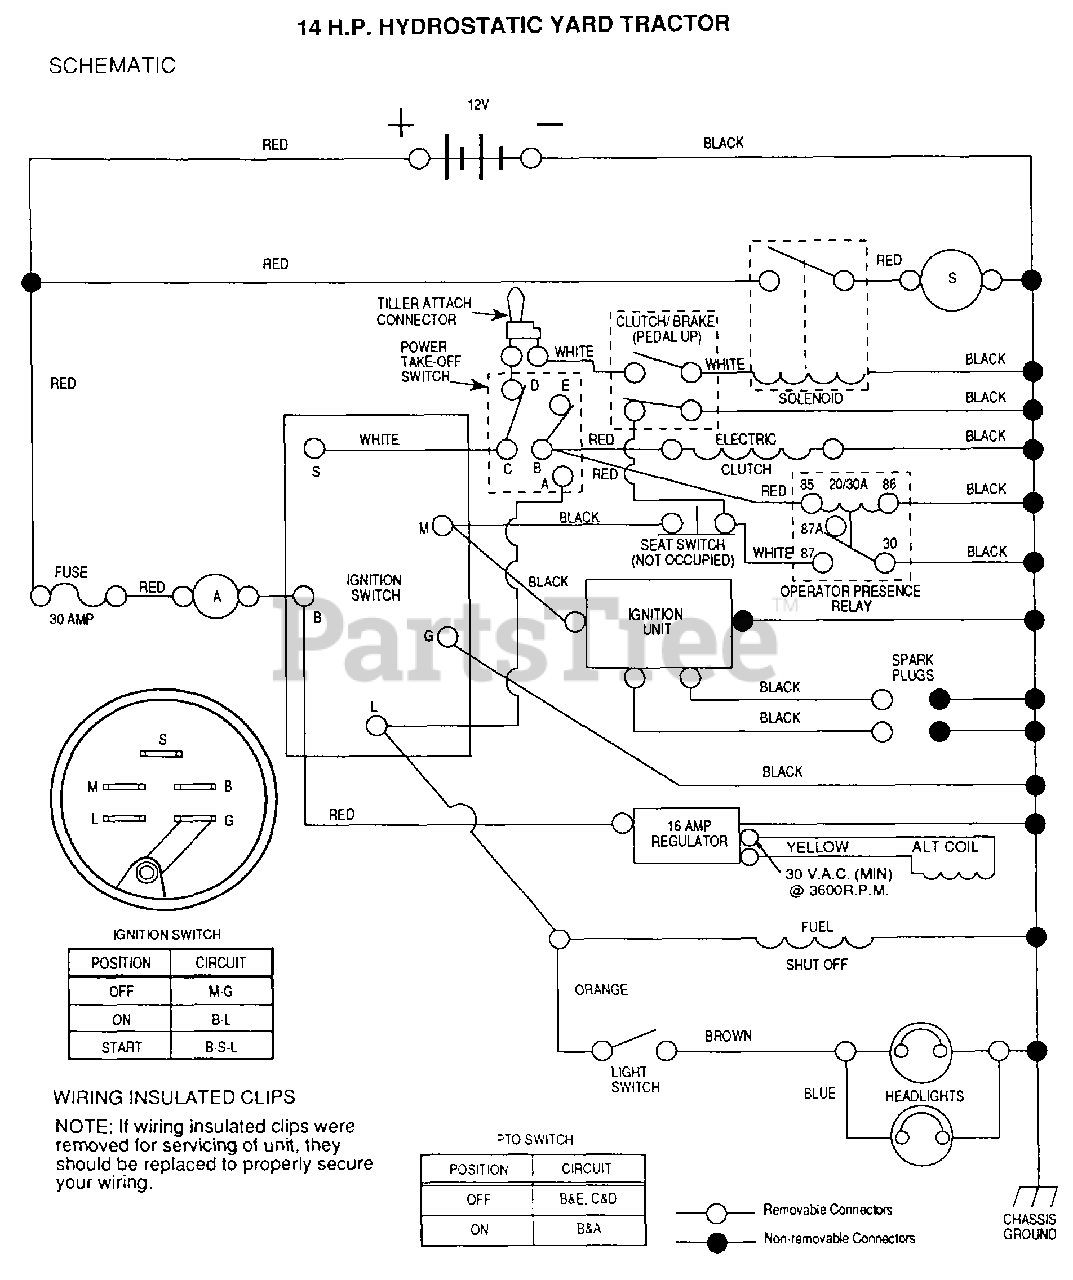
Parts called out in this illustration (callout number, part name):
2	RETAINIANG RING-(2003016)
3	BALL BEARING
4	SPACER
5	SEAL LIP
6	RING.RET.2003052
8	CRADLE BEARING (2003023)
11	BEARING
12	SEAL.9008000-0126
13	TRUNION ARM (2003005)
14	GUIDE.2000015.HYD
16	JOURNAL BRG(2003071)
19	CENTER SECTION
20	NEEDLE BEARING
21	LIP SEAL-9008000-0127
22	SHAFT
23	WASHER
30	SEAL LIP
31	CYLINDER BLOCK
32	CYLINDER BLOCK(70331)
34	PISTON SPRING
35	WASHER.TR.2003019
37	PIN
38	GASKET.20030600
39	FILTER
40	WASHER (2000011)
41	SPRING
45	SPRING.2003012.HY
46	PLUG
47	SCREW9007314-0808
50	WASHER
51	PIN
52	PLUG
53	O RING
56	BYPAS KT 25130011
57	O RING (9004175-0027)
58	ADHESIVE LABEL
59	PLUG
